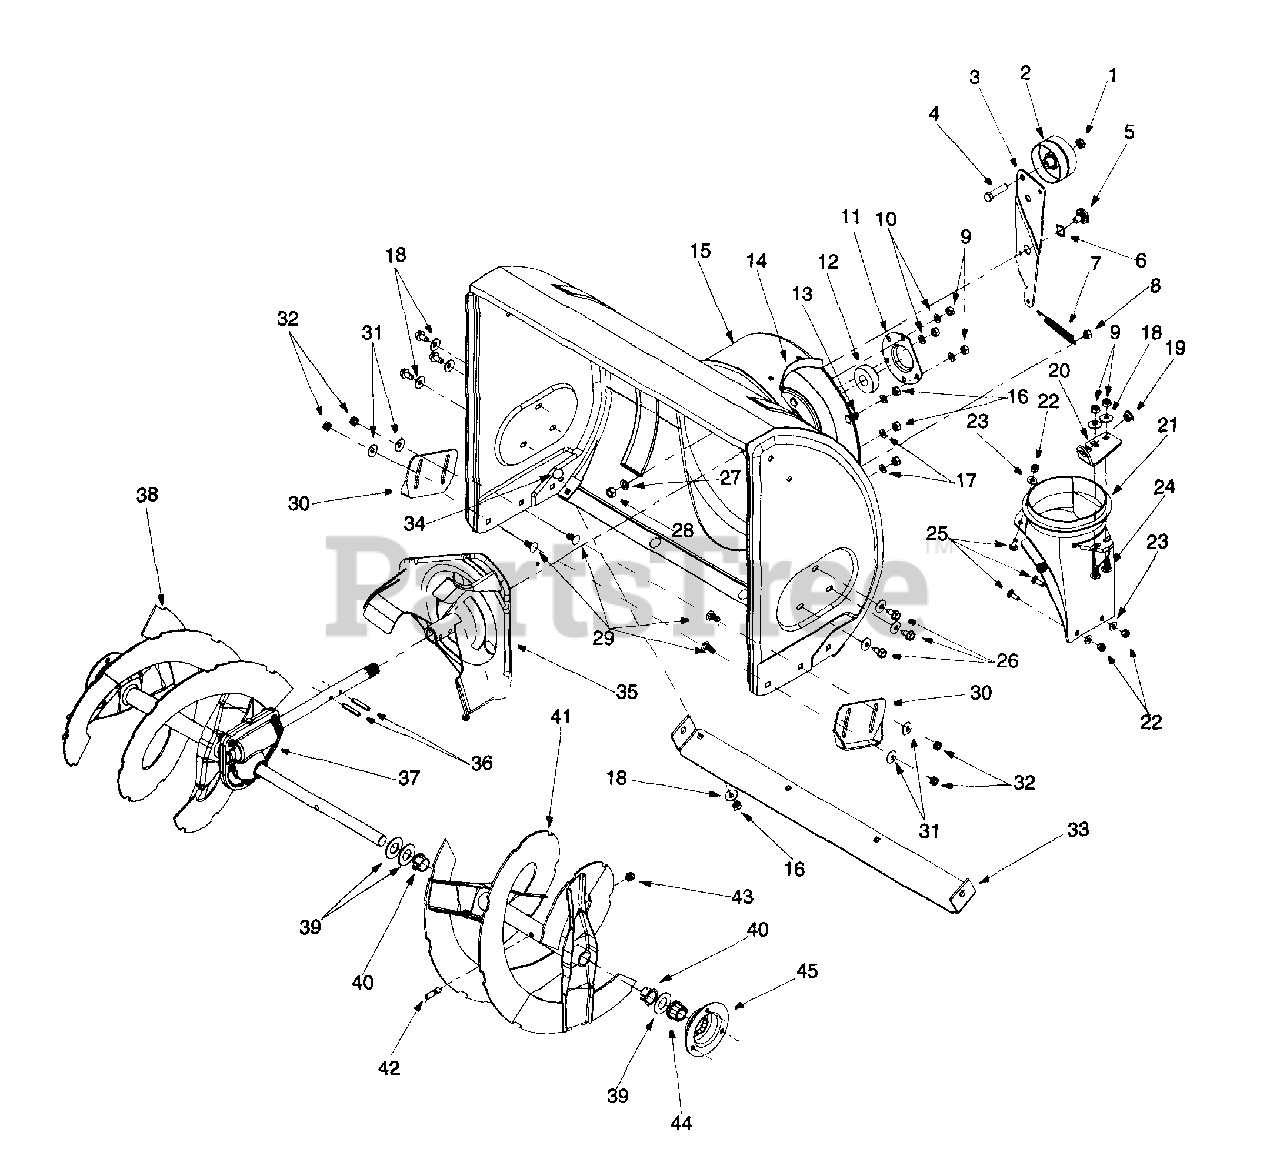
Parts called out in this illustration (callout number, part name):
1	Lock Jam Nut 3/8-24
2	Flat Idler
3	Auger Idler Arm
4	Hex Cap Screw 3/8-24 x 1.50
5	Shoulder Screw
6	Wave Washer
7	Extension Spring
8	Hex Nut 5/16-18
9	Hex Nut 5/16-18
10	Lock Washer 5/16
11	Housing
12	Ball Bearing
13	Carriage Bolt 5/16-18
17	Lock Washer 5/16
18	Bell Washer
19	Bushing
20	Chute Crank Bracket
21	Chute Adapter
22	Hex Lock Nut 1/4-20
23	Flat Washer
24	Carriage Bolt
25	Carriage Screw 1/4-20 x .75
26	Hex Washer Screw 5/16-18
27	Lock Washer 3/8
28	Hex Nut 3/8-16
29	Carriage Bolt 5/16-18 x .75
31	Bell Washer
32	Hex Nut 5/16-18
33	24" Shave Plate
33	26" Shave Plate
34	Carriage Bolt 5/16-18 x .62
35	Impeller Assembly
36	Pin
37	24" Gear Assembly
37	26" Gear Assembly
38	Spiral 24" RH
38	Spiral 26" RH
39	Flat Washer
40	Flange Bushing
41	Spiral 24" LH
41	Spiral 26" LH
42	Shear Bolt 5/16-18 x 1.5
43	Lock Nut 5/16-18
44	Hex Flange Bearing
45	Bearing Housing
